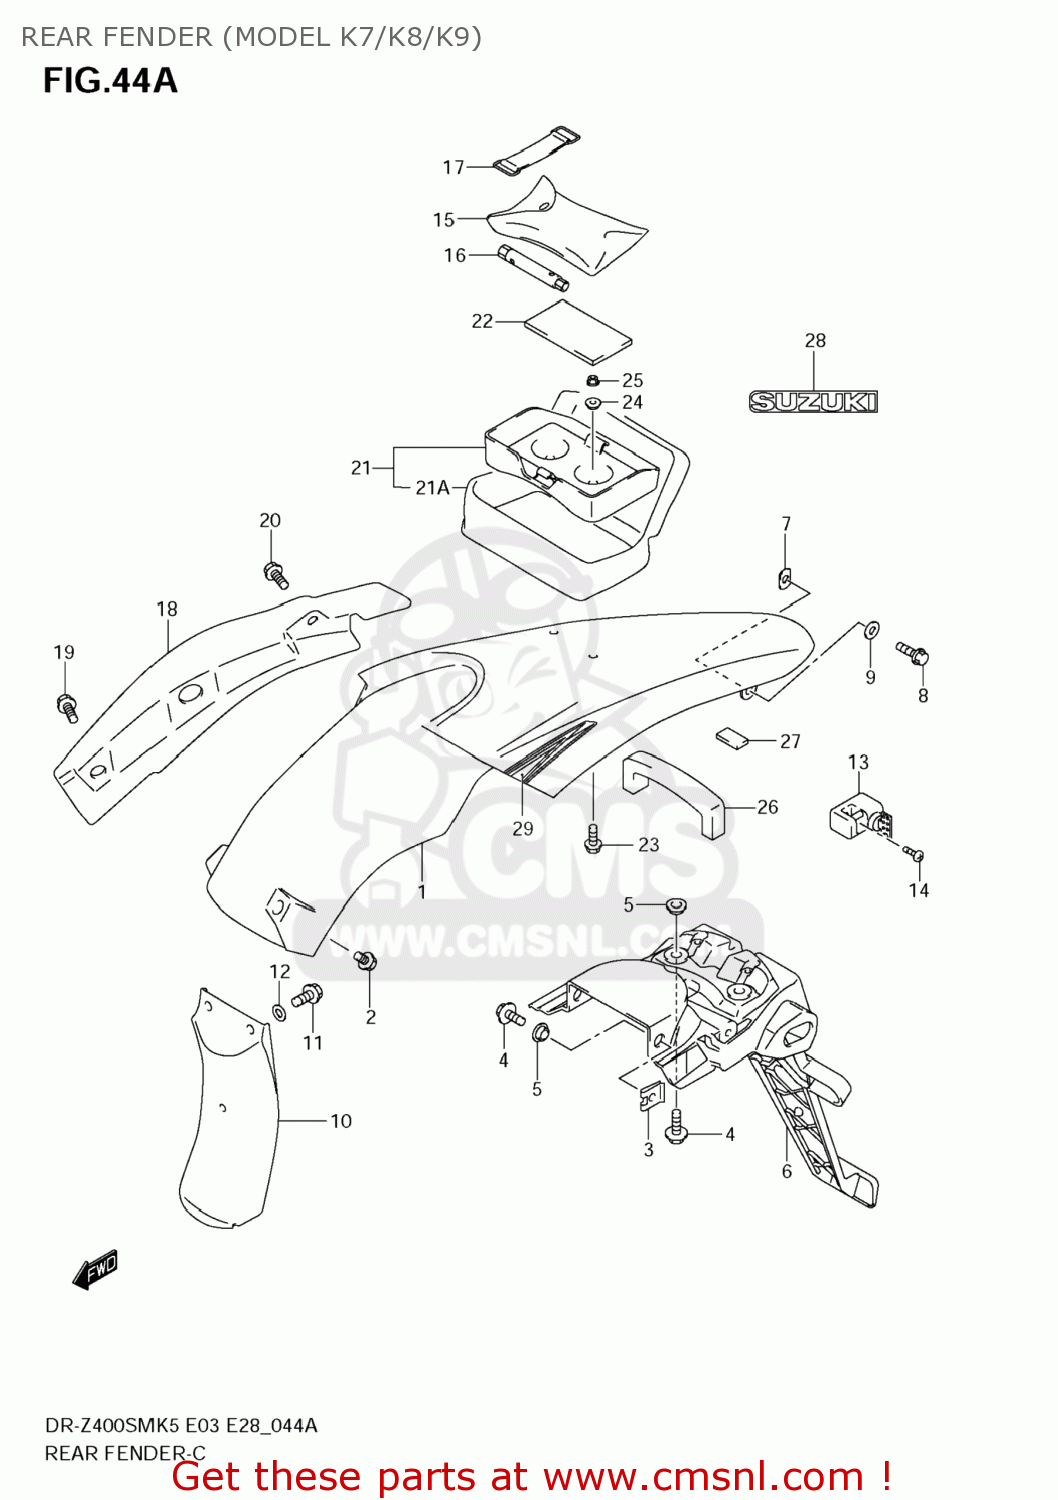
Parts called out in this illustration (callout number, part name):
1	FENDER,RR
2	BOLT(6X16)
3	PLATE,RR FENDER
4	BOLT(6X20)
5	WASHER
6	EXTENSION,RR FENDER
7	NUT,COWL
8	BOLT
9	WASHER
10	MUDGUARD,RR FENDER FR
11	BOLT
12	WASHER
13	LOCK SET,HELMET
14	SCREW(6X14)
15	TOOL ASSY
16	SPARK PLUG WRENCH(8X10)
17	BAND
18	MUDGUARD,RR FENDER,R
19	BOLT(6X18)
20	BOLT
21	BAG ASSY,SEAT TAIL
21A	BAG,SEAT TAIL
22	CUSHION,RR BAG
23	BOLT
24	WASHER
25	NUT
26	SEALER,SIDE COVER L
27	PROTECTOR(170X95X3.0)
28	EMBLEM,SUZUKI
29	TAPE SET,RR FENDER
